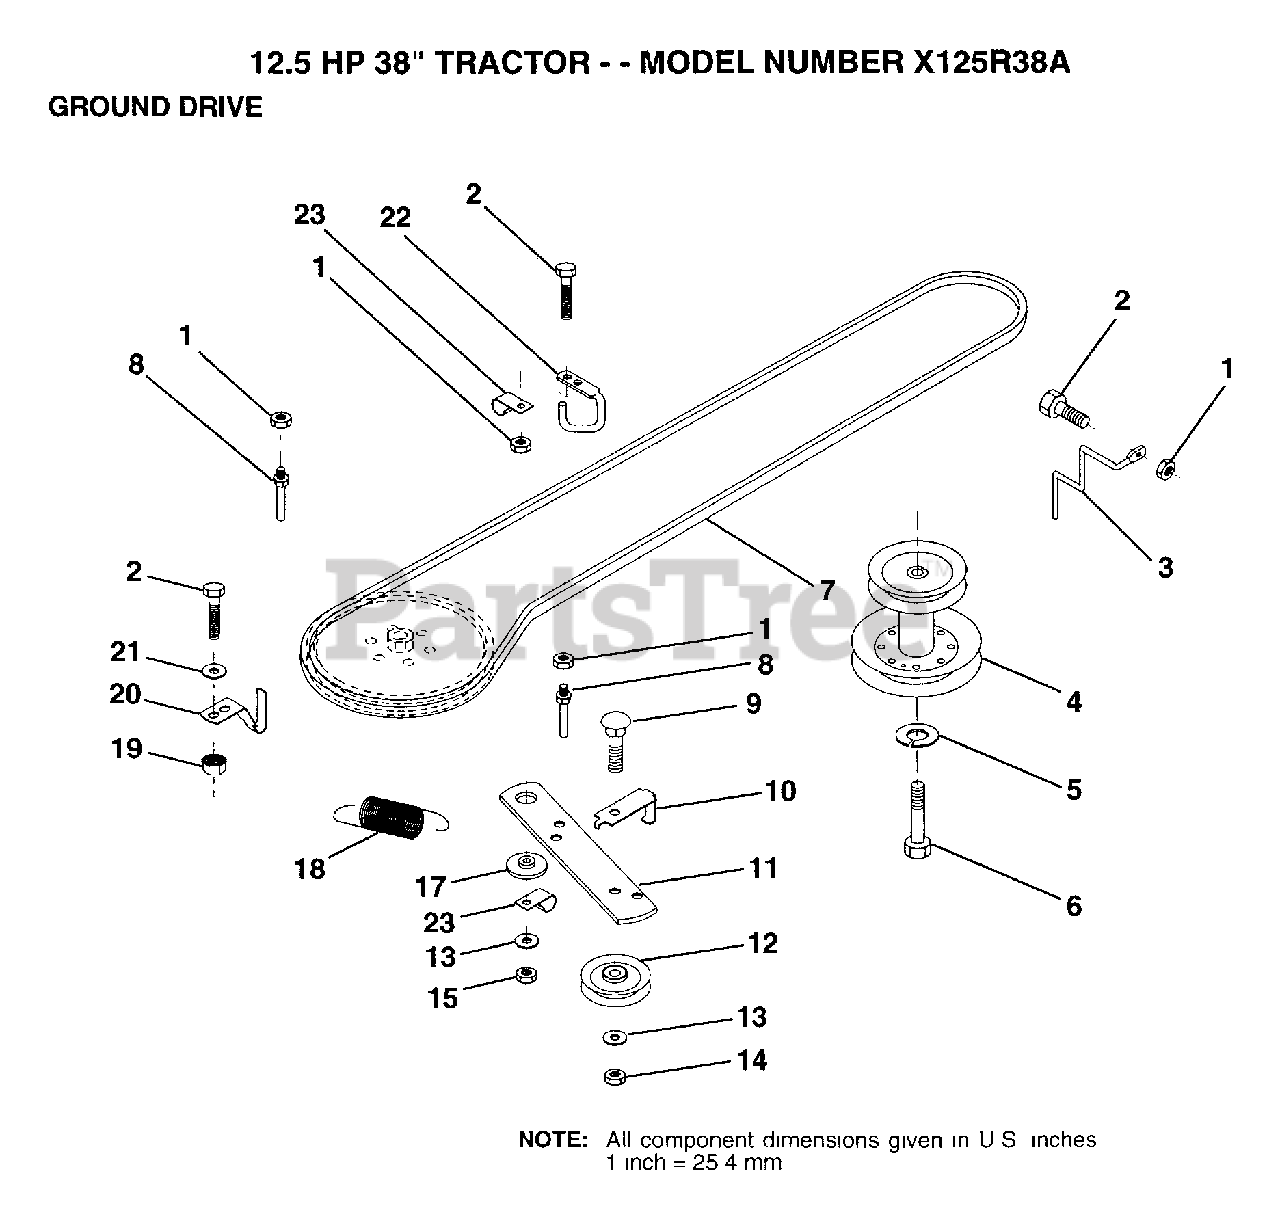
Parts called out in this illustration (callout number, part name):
2	BOLT
3	KEEPER MWR DR BLT
4	PULLEY.ENGINE.LR
5	LOCKWASHER
6	HEX BOLT
7	BELT
8	"KEEPER,DRIVE BELT"
9	BOLT
10	"KEEP,IDLER DR BEL"
12	PULLEY IDLER
13	WASHER
14	LOCKNUT
17	SPACER RETAINER
20	"KEEPER,DR BELT "
21	WASHER
22	"KEEPER,FRA DR BEL"
23	CLIP INSULATOR
